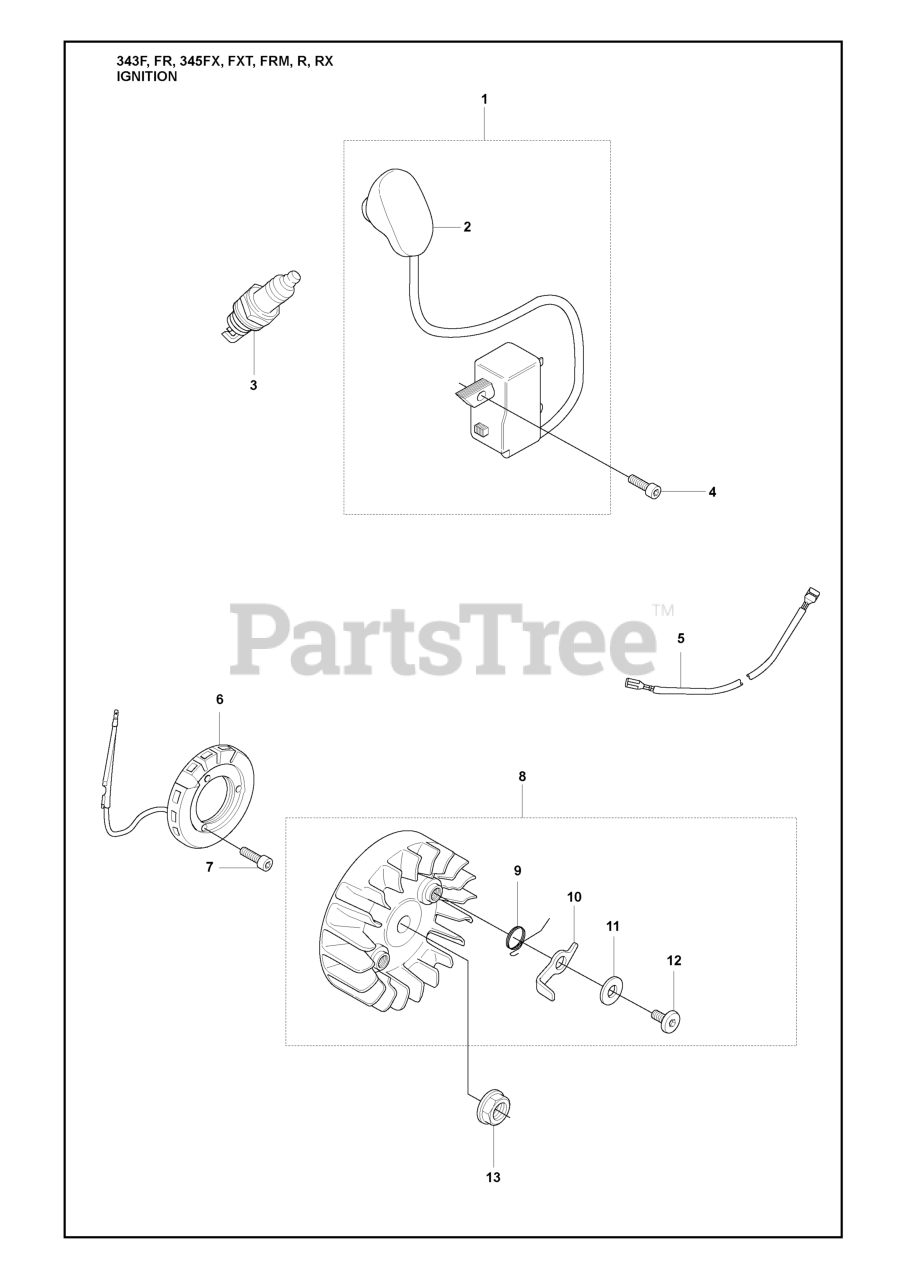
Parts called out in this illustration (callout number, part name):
1	IGNITION MODULE
3	Spark Plug, RCJ6Y
5	SHORTING LEAD
6	GENERATOR
7	SCREW
8	FLYWHEEL
9	SPRING
10	STARTER PAWL
13	NUT W/ WASHER
